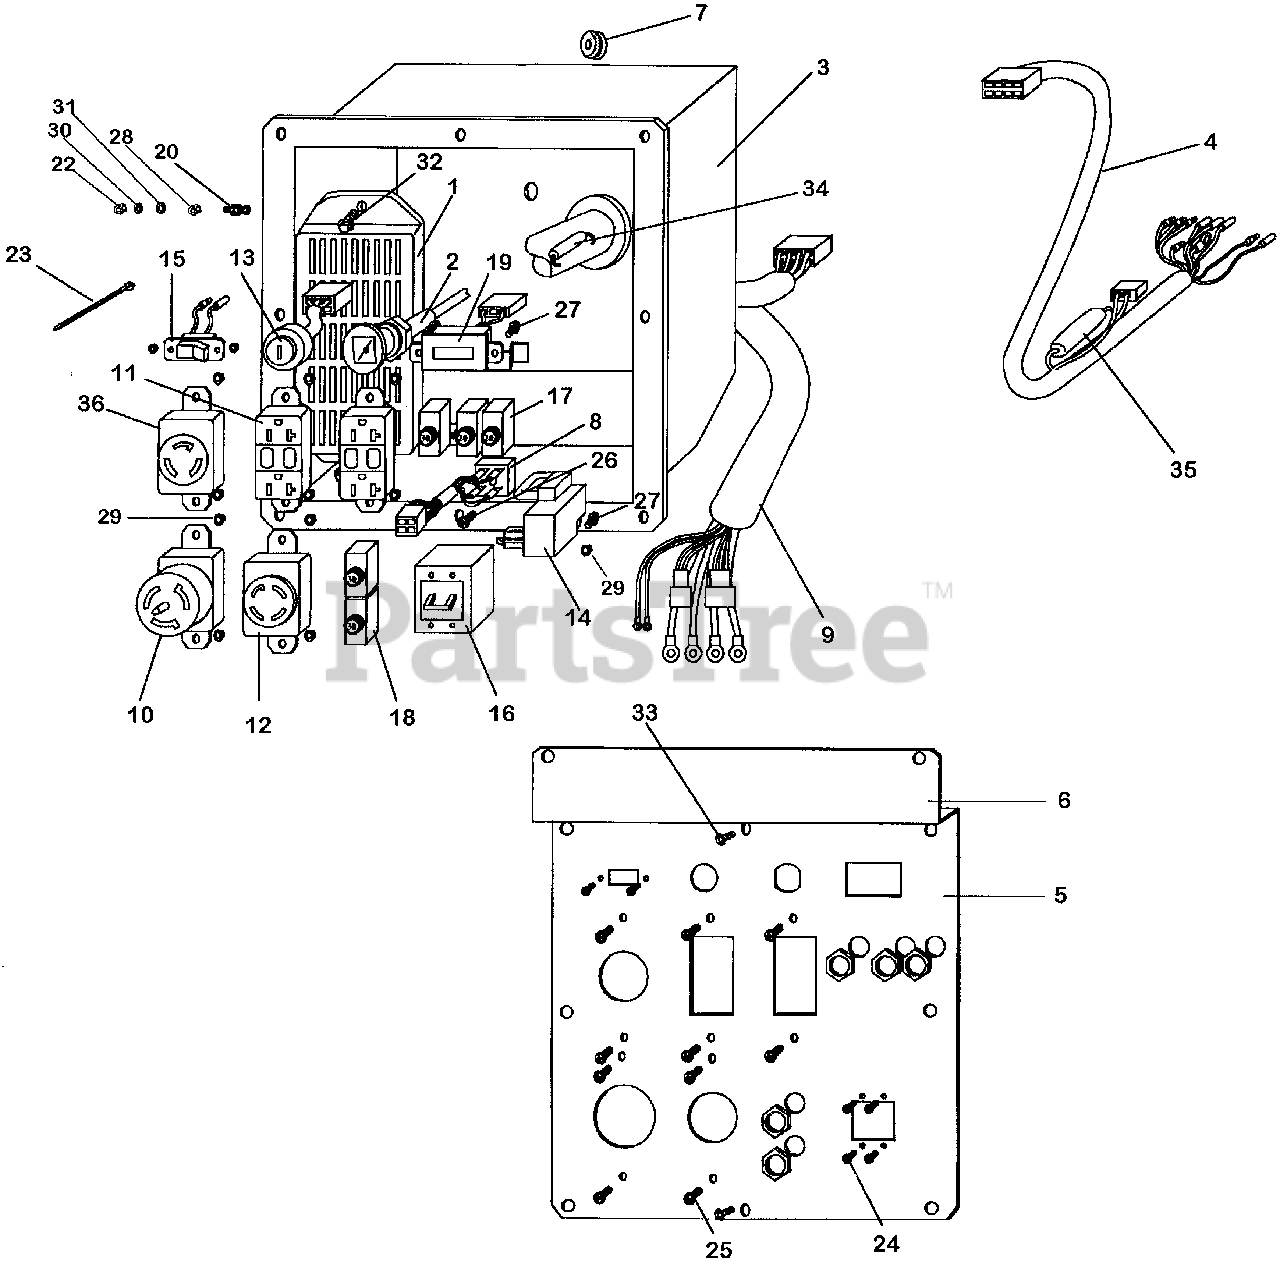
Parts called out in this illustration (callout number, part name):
1	A.V.R. ASSY.
2	CABLE, CHOKE
3	COVER, CONTROL BOX
4	HARNESS ASSY., ENG.
5	MARK, PANEL PLATE
6	PANEL, CONTROL
7	GROMMET, CHOKE CABLE
8	DIODE ASSY.
9	HARNESS ASSY., GENERATOR
10	RECEPTACLE (50A/125-250V)
11	RECEPTACLE (20A/125V)
12	RECEPTACLE (3-PRONG) (30A/125V)
13	SWITCH ASSY., COMBINATION
14	THROTTLE UNIT, AUTO (SAWAFUJI)
15	SWITCH, AUTO THROTTLE
16	BREAKER (41A)
17	PROTECTOR, CIRCUIT (20A)
18	PROTECTOR, CIRCUIT (30A)
19	METER ASSY., HOUR
20	BOLT, HEX. (6X28)
22	RETAINER (6MM)
23	TIE, CABLE (C)
24	SCREW, PAN (3X6)
25	SCREW, PAN (4X12)
26	SCREW-WASHER (4X20)
27	SCREW-WASHER (5X16) Use up to Engine SN 2056819.
28	NUT, HEX. (6MM)
29	NUT, FLANGE (4MM)
30	WASHER, PLAIN (6MM)
31	WASHER, SPRING (6MM)
32	BOLT, FLANGE (8X16) Use from Engine SN 1000016.
33	BOLT, FLANGE (6X12) Use from Frame SN 1001725.
34	FUSE B (5A)
35	FUSE B (10A)
36	RECEPTACLE (30A/125-250V)
